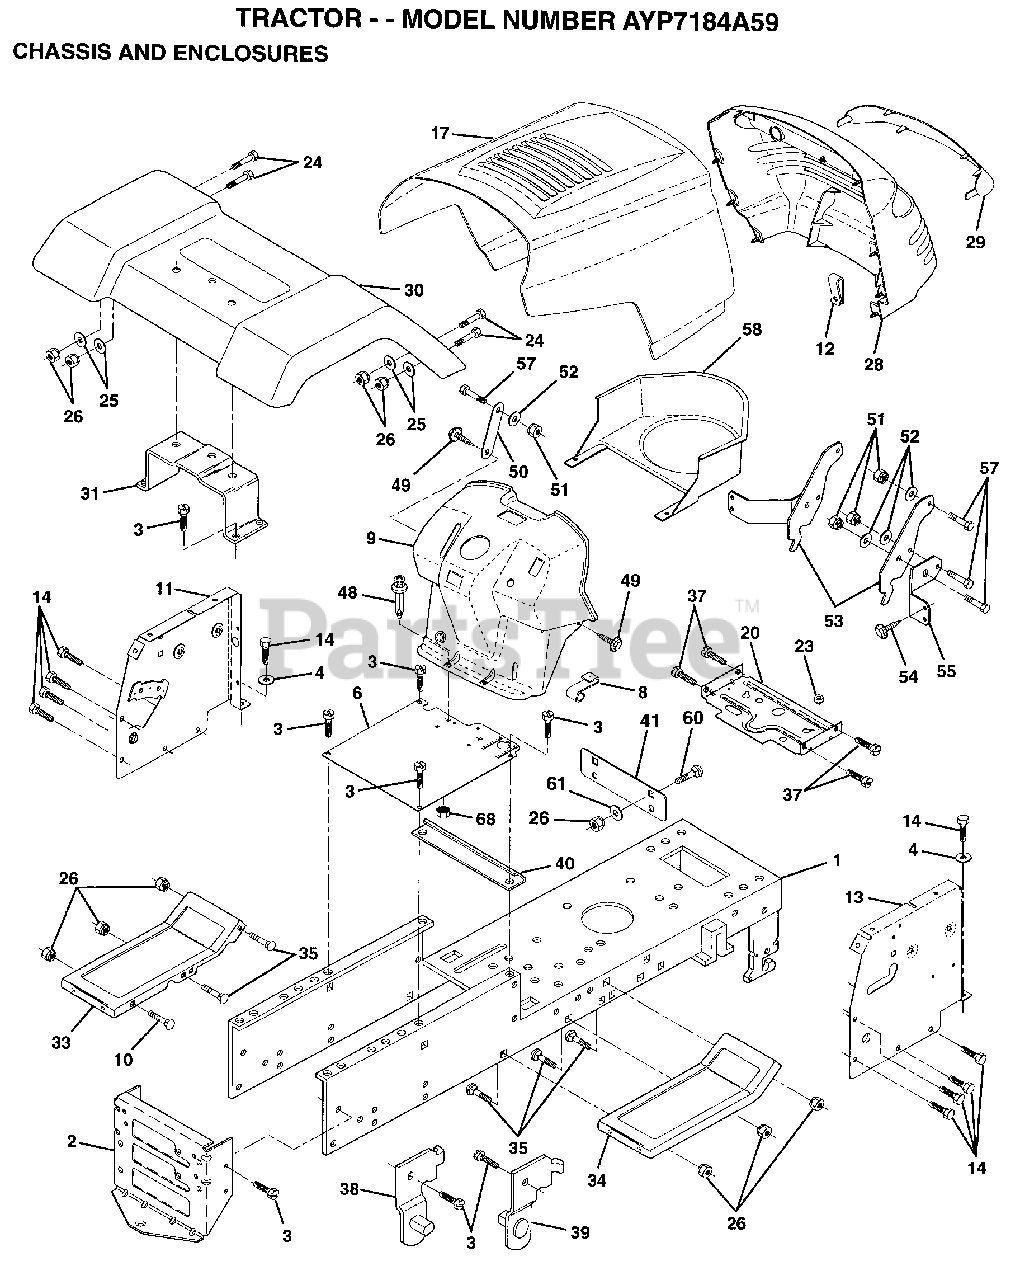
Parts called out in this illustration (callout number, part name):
1	CHASSIS.WLD.11GA
3	SCREW
4	WASHER
8	"CLIP,INSULATOR"
12	CLIP.TINNERMAN
14	SCREW LT
24	BOLT
25	WASHER
26	NUT
29	LENS GRILLE
30	FENDER
31	BRACKET SUPT FEND
33	FOOTREST LH
34	FOOTREST RH
35	BOLT
37	SCREW
38	BRACKET ASM LH
39	BRACKET ASM RH
40	SPACER FENDER LT
41	PLATE EXTEN FEND
48	RIVET.PUSH.PLATE
49	SCREW HEX CRT
50	BRACE SUPT DASH
51	NUT
52	WASHER
53	HING PICK-OFF HD
55	BRACKET GRILLE
58	DUCT AIR 12-15H
60	BOLT
61	WASHER
68	NUT
